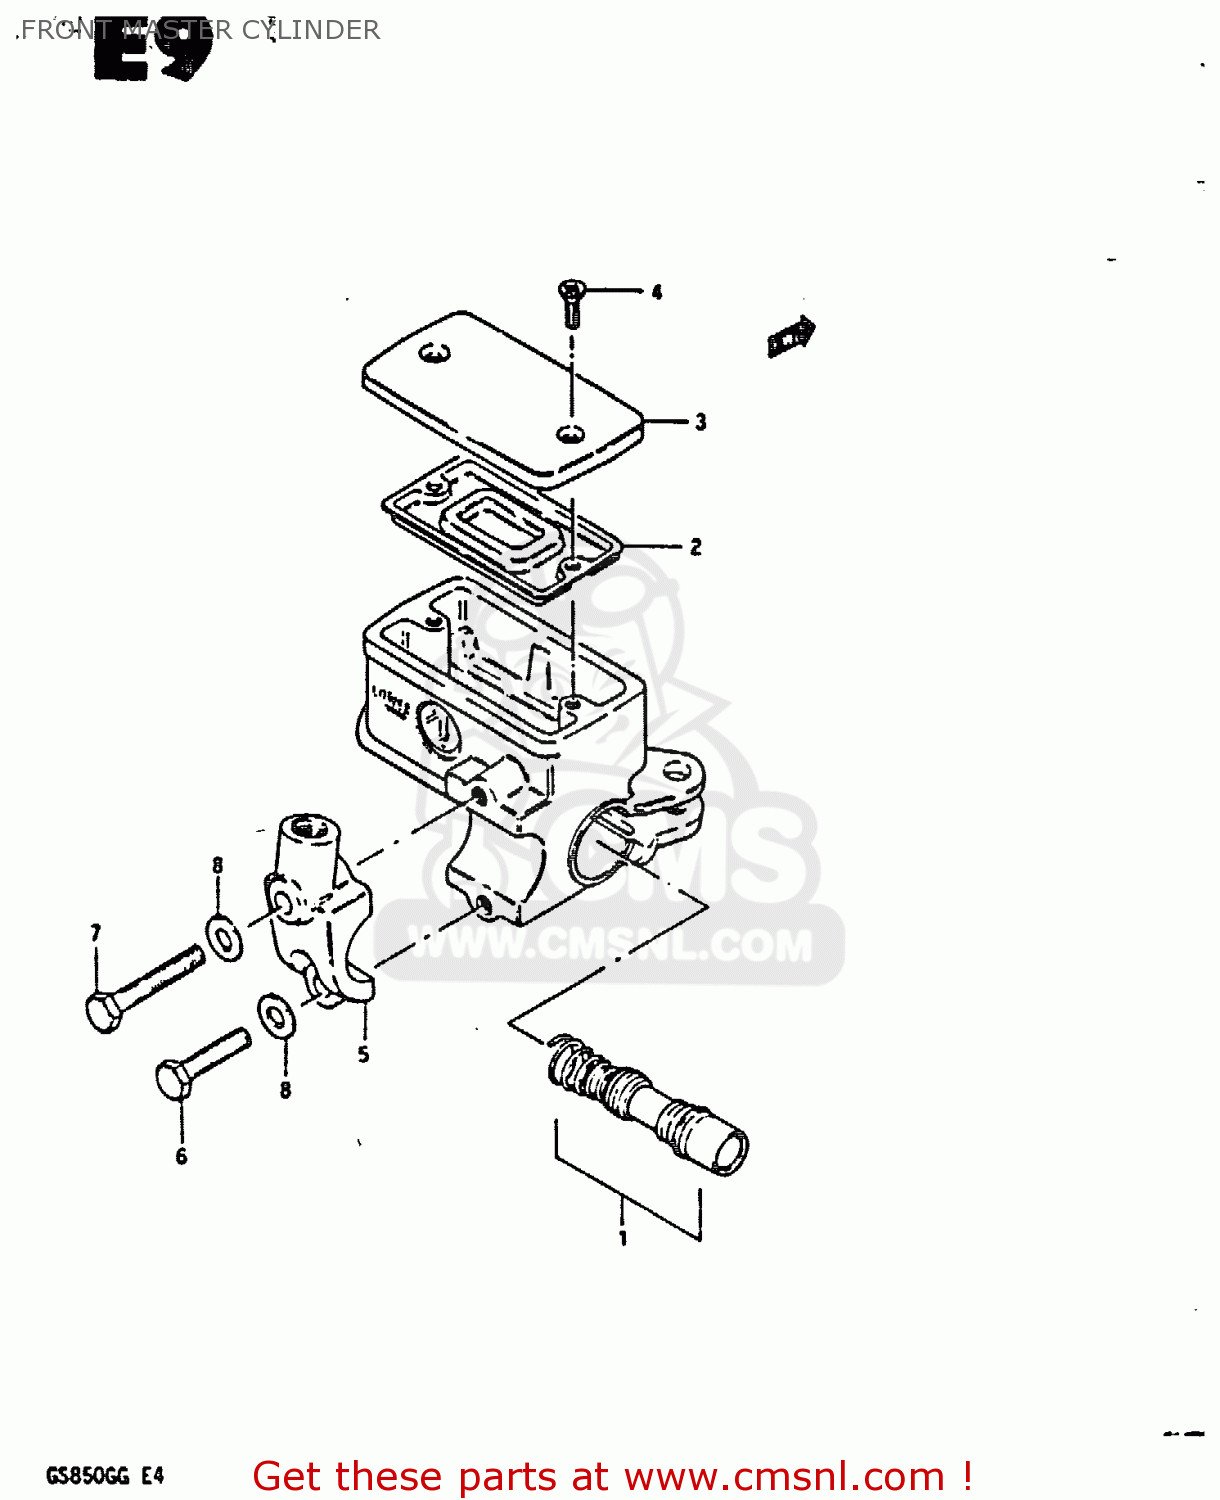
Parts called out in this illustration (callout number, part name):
1	PISTON & CUP SET
2	3-1
3	CAP
4	SCREW
5	HOLDER
6	BOLT
7	BOLT
8	WASHER
